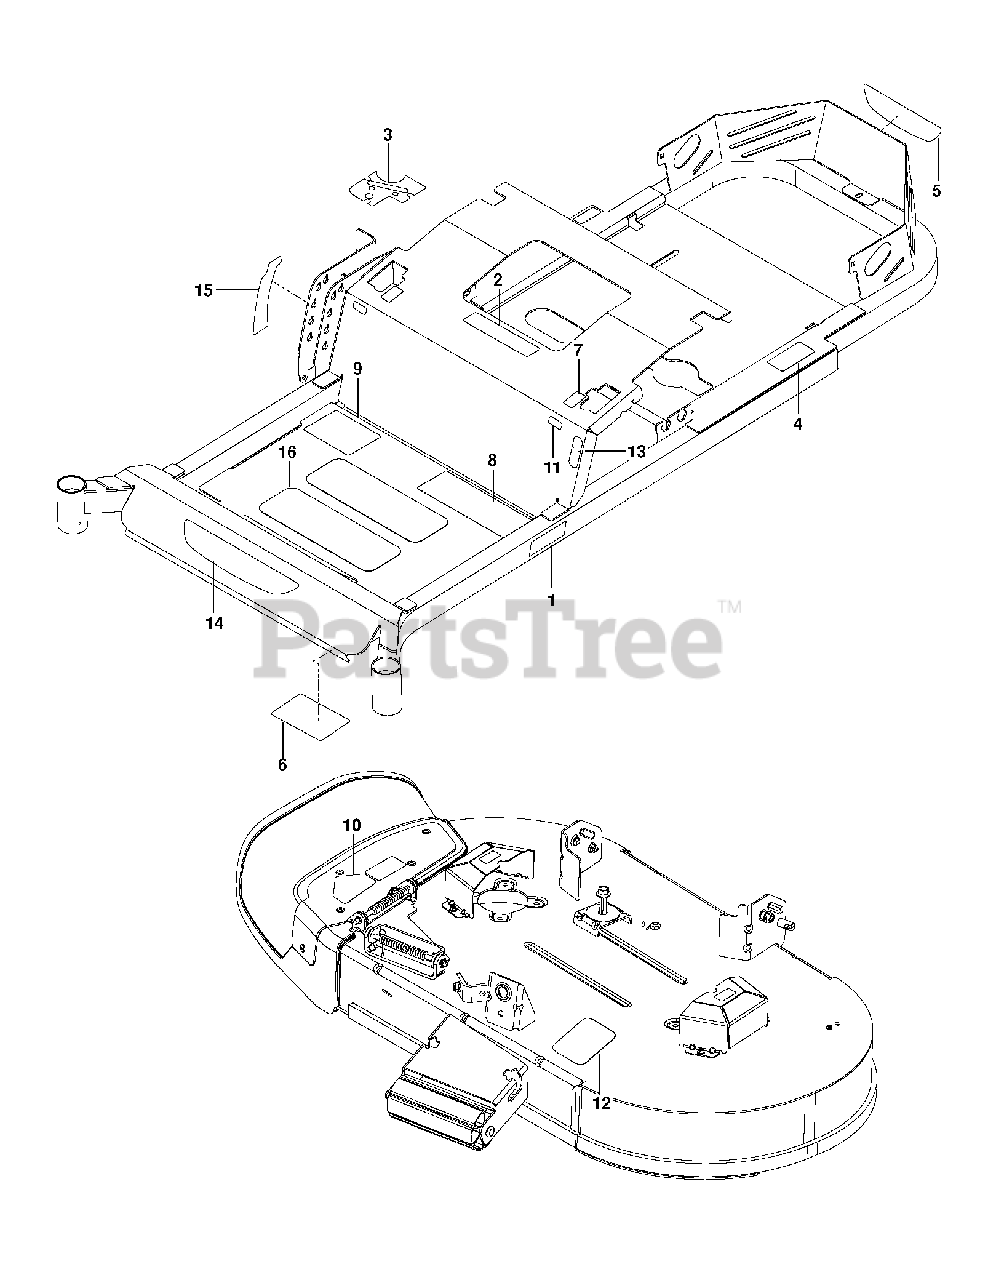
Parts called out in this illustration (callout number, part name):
2	DECAL, BATTERY
4	DECAL, DO NOT MOUNT
6	DECAL, SERVICE
8	DECAL, SAFETY WARNING
9	DECAL ZTR STARTING DECAL
10	DECAL.TRACT/ZTR.DECKWARN.JONS
12	DECAL, BELT ROUTING
16	ANTI-SKID PAD
